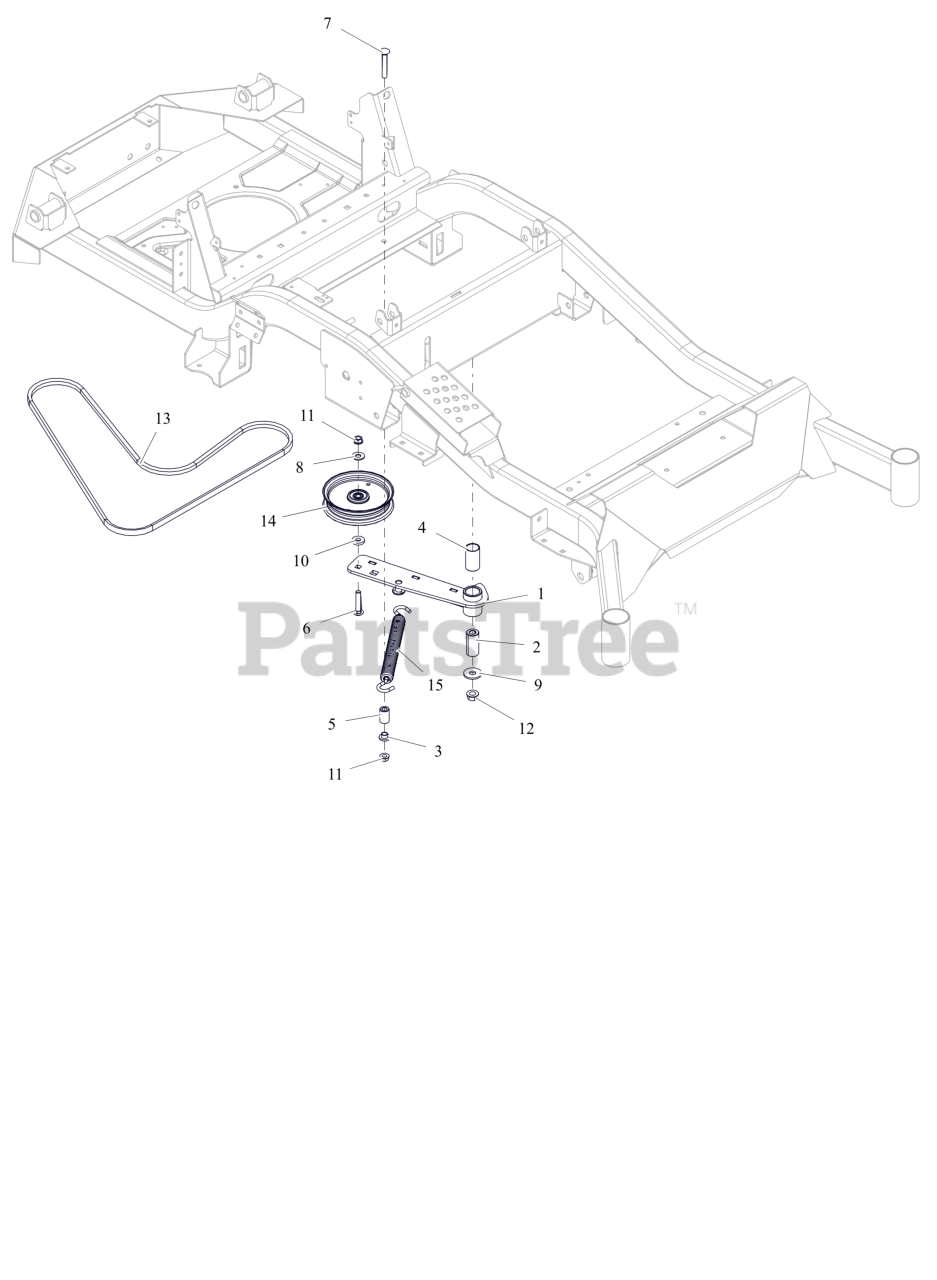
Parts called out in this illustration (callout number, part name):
1	WLDMT, HYDRO DRIVE IDLER ARM (BLACK)
2	BSHG, SPCR .502X.997X2.03 PM
3	BSHG-FLG .385X.500X.875X.406
4	BSHG, 1.00X1.125X1.937
5	BUSHING, SLV .380X.750X1.190
6	BLT, RHSN .38-16X2.00 G5 ZCC
7	BLT, RHSSN.38-16X2.50 G5 ZCC
8	WSHR,FLT .438X1.00X.083 ZCC
9	WSHR-FL-STL.511X1.44X.125ZC120
10	WSHR, FLT .406X1.00X.188 ZCC
11	NUT-LK-TOP-FLG .38-16 ZC120
12	NUT-LK-TOP-FLG .500-13 GF ZCC
13	V-BELT, 4L-WRAPPED
14	IDLER- FLAT - 5.00" X .75"
15	SPRING, EXTENSION
